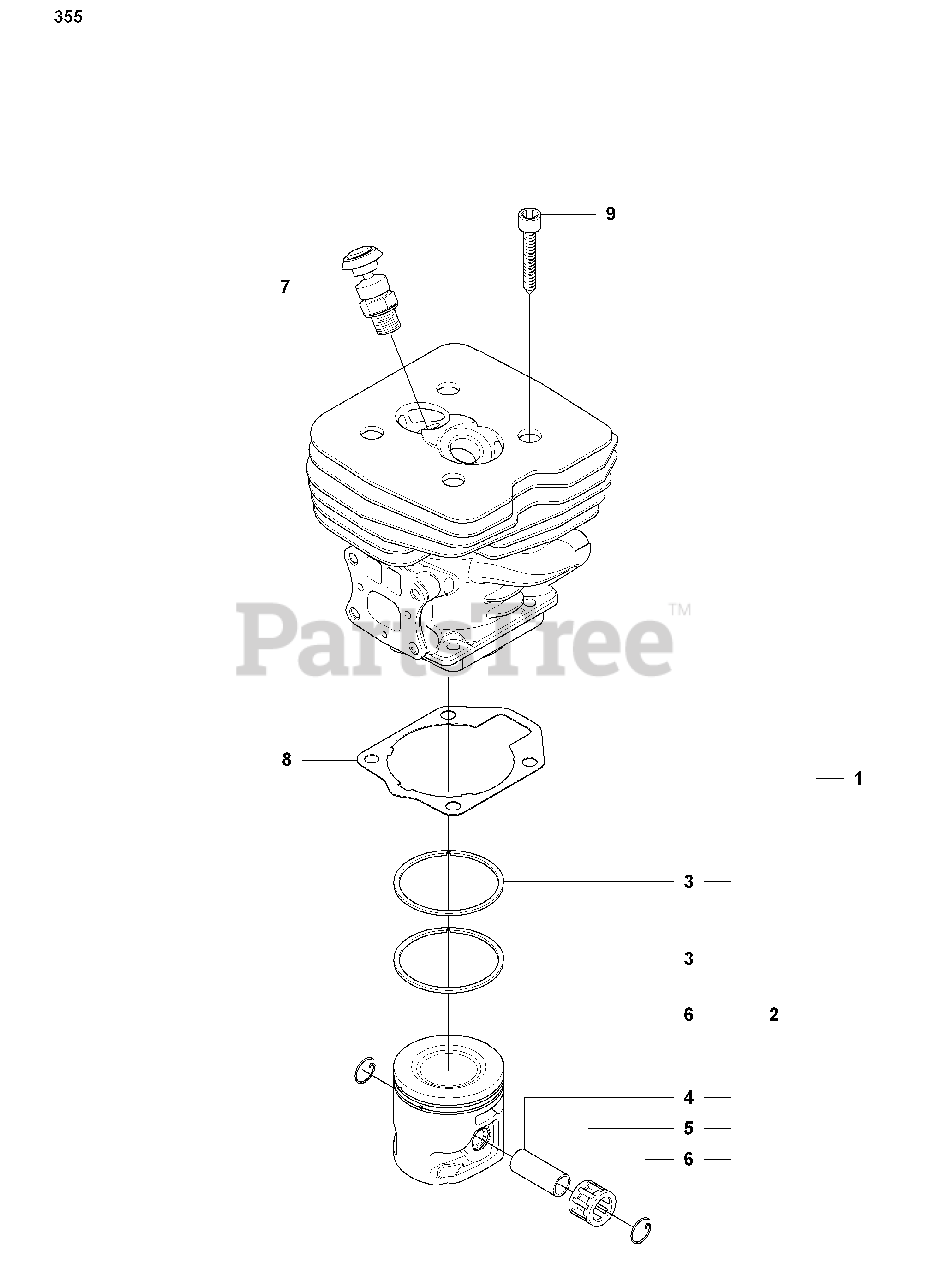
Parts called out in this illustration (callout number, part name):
1	CYLINDER ASSY
2	%PISTON ASSY
3	PISTON RING
4	PISTON PIN
5	SUPPORT BUSHING
7	DECOMPRESSION VALVE
9	SCREW MC6S 5X25
